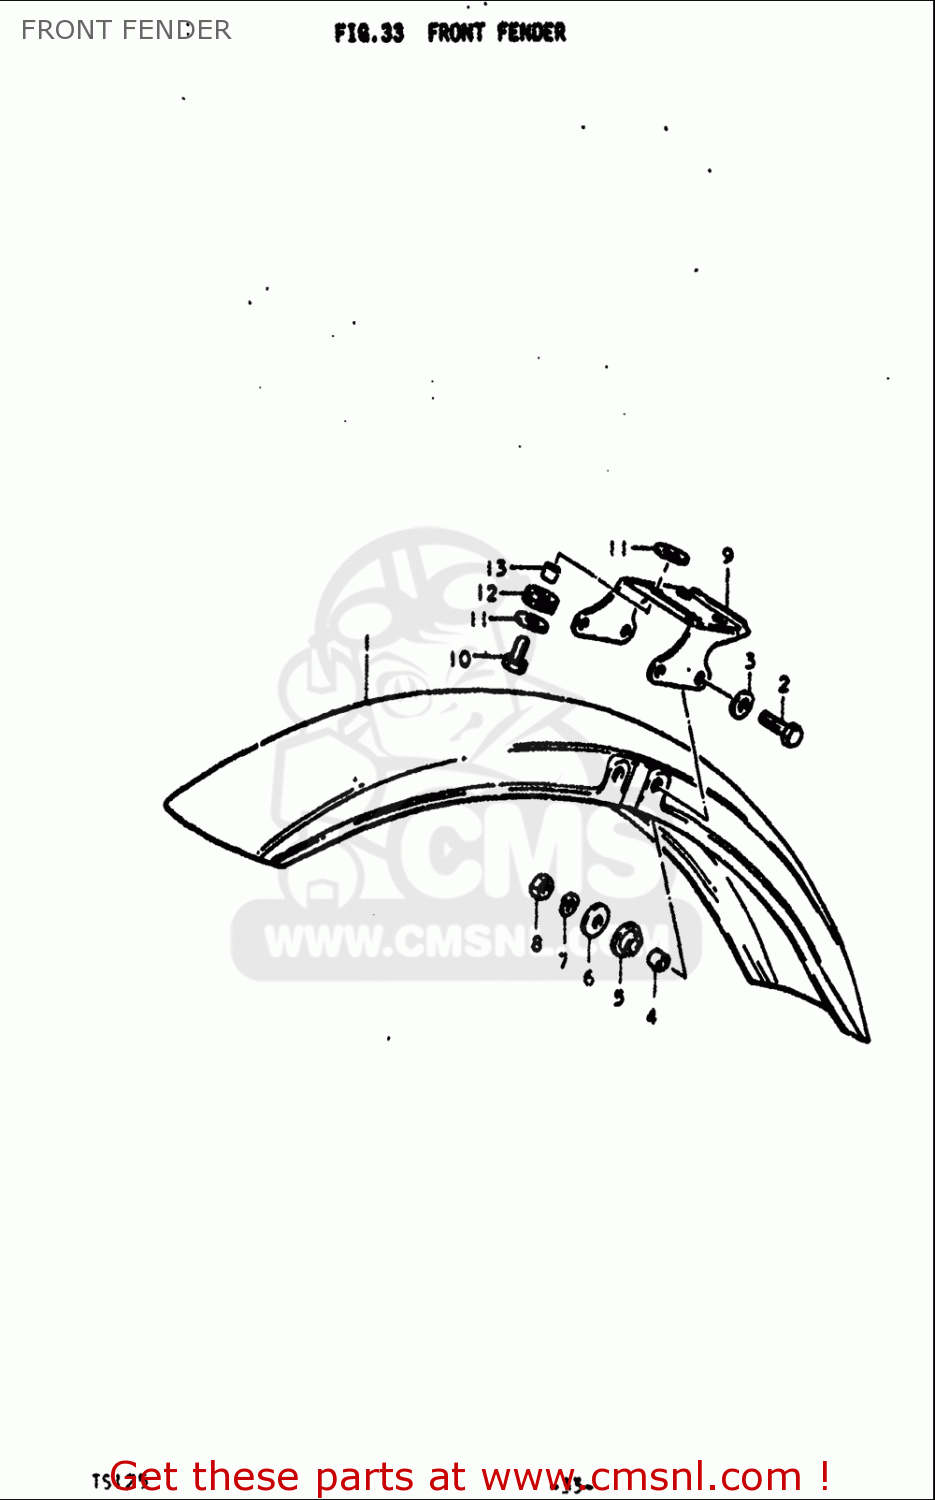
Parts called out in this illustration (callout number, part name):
2	BOLT
3	WASHER
4	SPACER
6	WASHER(6.5X20X1.2)
7	WASHER,LOCK
8	NUT
9	BRACE,FRONT FENDER
10	BOLT
11	WASHER(6.5X20X1.2)
13	SPACER(6.1X9X7.5)
